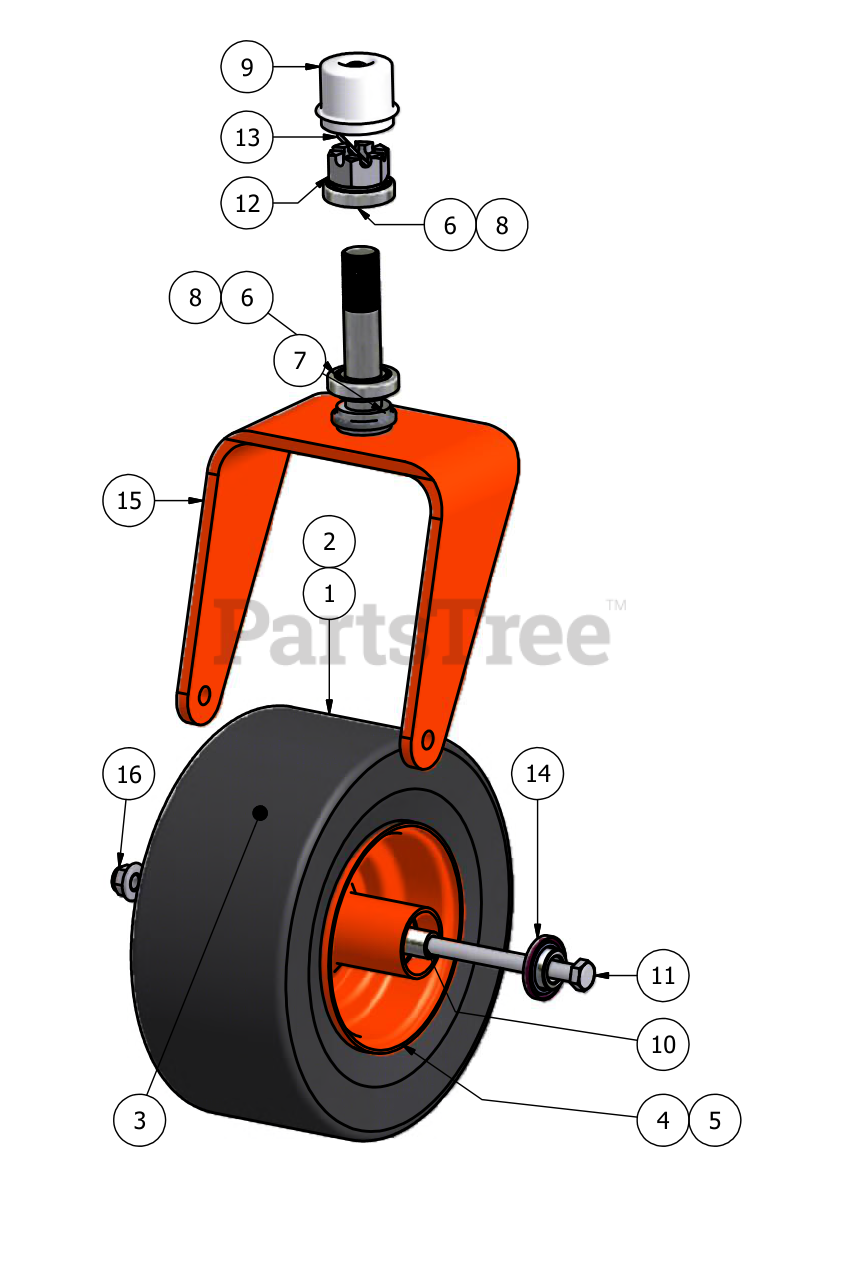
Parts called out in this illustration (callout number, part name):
1	13 x 6.5-6" Tire and Wheel Assembly
2	13 x 6.5-6" Assembly for 36" ZT
3	13 x 6.5-6" Tire ONLY
4	6" Wheel ONLY
5	6" Silver Wheel for 36" ZT
9	Dust Cover
10	Wheel Spacer
11	1/2" x 9" Bolt
12	1" Fine Threaded Castle Nut
13	1/8" x 2 1/4" Cotter #8
14	Wheel Bearing
15	Front Fork with
16	1/2" Flange Lock Nut
